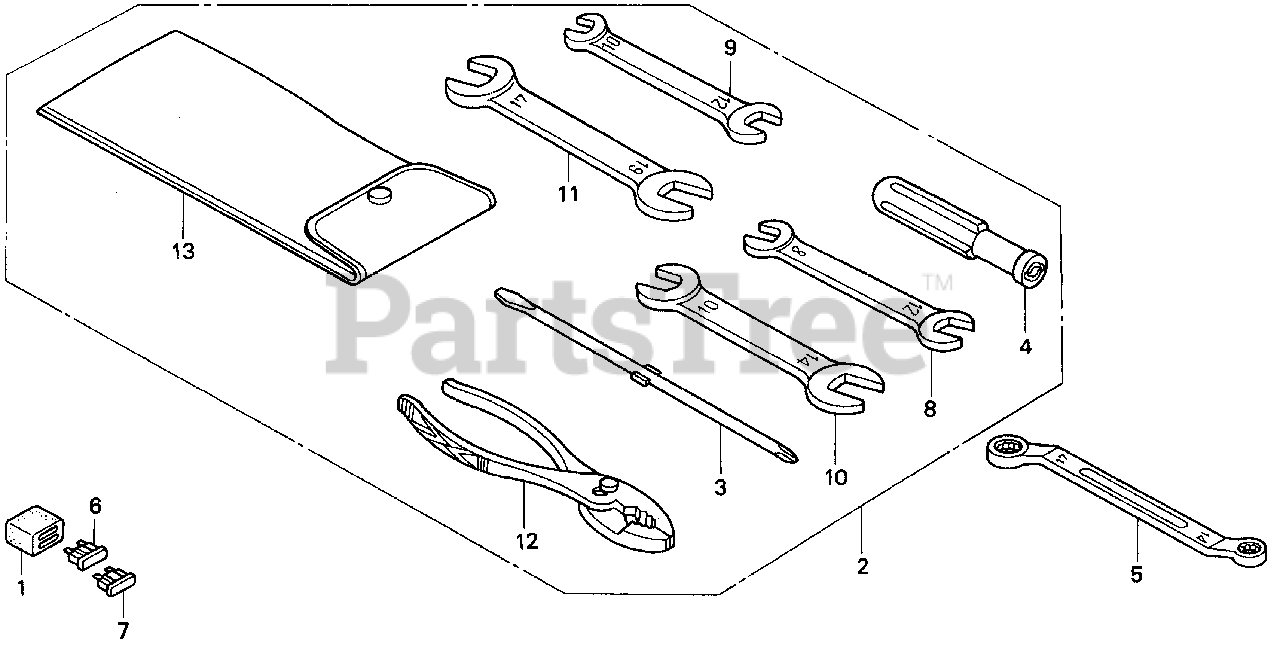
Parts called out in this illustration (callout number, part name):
1	SUSPENSION, TURN SIGNAL RELAY
3	SHAFT, SCREWDRIVER
5	WRENCH, EYE (14X17)
6	FUSE, BLADE (5A)
7	FUSE, BLADE (10A)
8	WRENCH (8X12) (OPEN END)
9	WRENCH (10X12) (OPEN END)
10	WRENCH (10X14) (OPEN END)
11	WRENCH (17X19) (OPEN END)
12	PLIERS (150MM) (NOT AVAILABLE)
13	BAG, TOOL (230MM)
